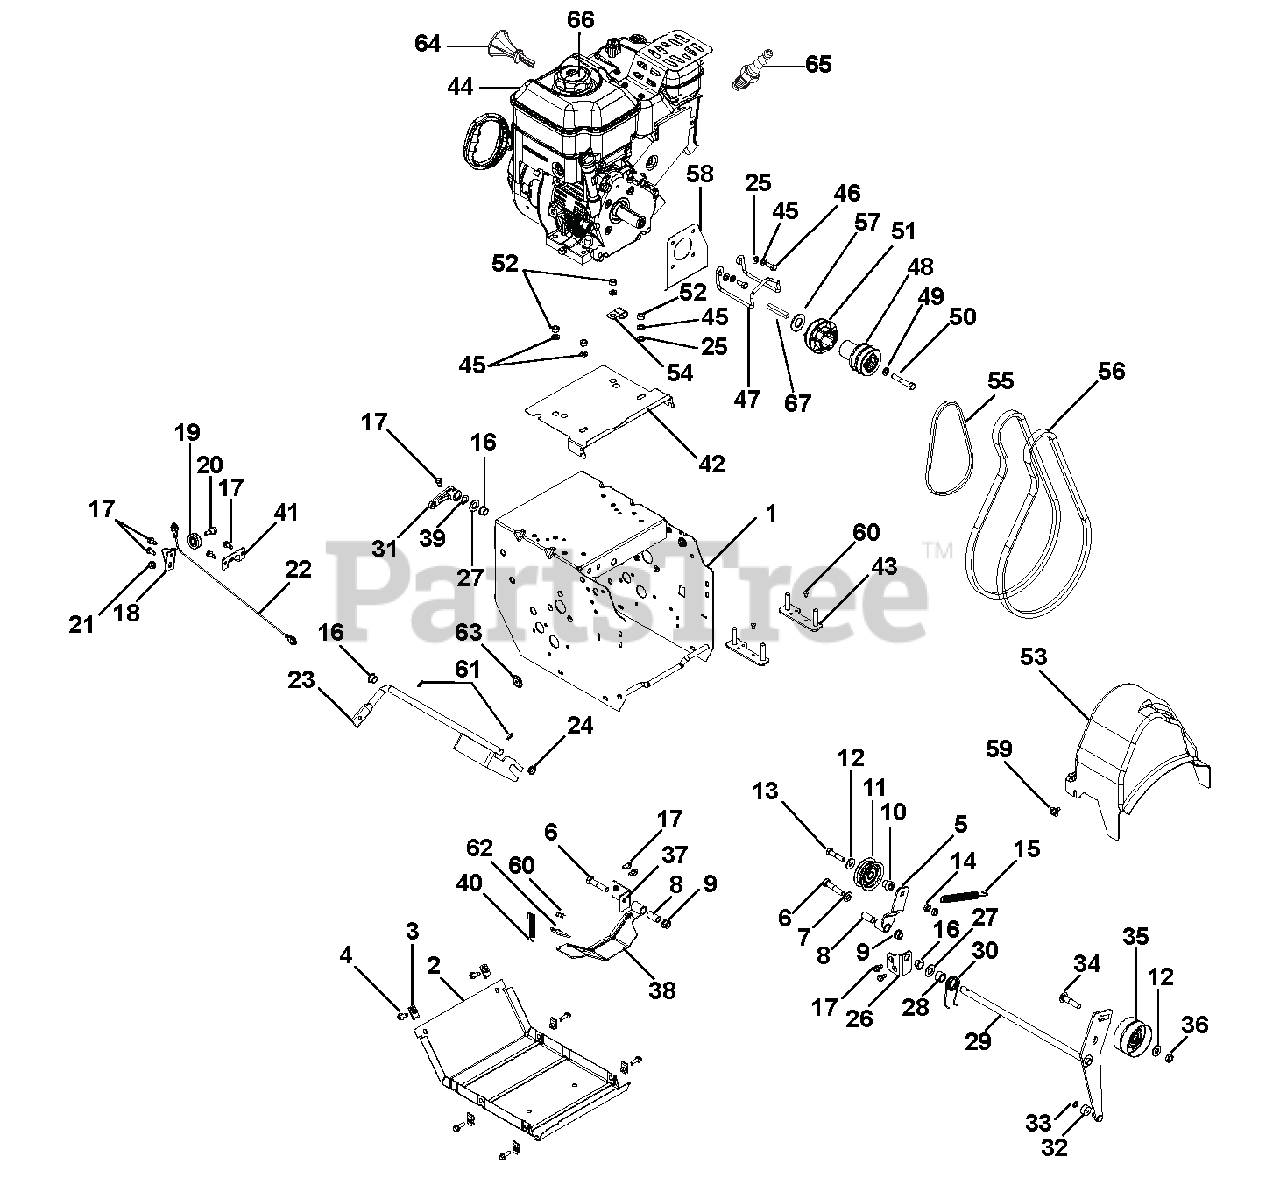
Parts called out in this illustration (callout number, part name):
1	FRAME, 920/921
2	COVER, BOTTOM
3	NUT-RTNR .25-20X.56
4	BLT-HEX .25-20X.75 HWH YZ GR5
5	WELDMENT, TRACTION IDLER ARM
6	@BLT-HEX .38-16X1.75 GR5 YWZC
7	@WSHR-FL-STL.406X.812X.065 YWZ
8	BSHG-SLV .385X.500X1.045
9	@NUT-LK-TOP-FLG .38-16 YWZC
10	SPCR, BRG .315X.50X.688X.281
11	IDLER
12	@WSHR-FL-STL.38X.875X.083 YWZC
13	@BLT-HEX .31-18X1.50 GR5 YWZC
14	@NUT-LK-CTR-JAM .31-18 YWZC
15	SPRING, EXTENSION
16	BUSHING, POLYLINER-.50 SPLIT
17	SCR-TAP .25-20X.50 HWH TR YWZ
18	BRACKET, CABLE PULLEY
19	PULLEY, CABLE
20	BOLT, SHLDR-.375X.375X.25-20
21	@NUT-LK-TOP-FLG .25-20 YWZC
22	CABLE, LOWER TRACTION (DELUXE)
23	WELDMENT, SHIFT FORK
24	BUSHING, POLYLINER-.50 SNAPIN
25	@WSHR-FL-STL.344X.688X.065YWZC
26	BRACKET, MOUNT - IDLER ARM
27	WSHR-FL-STL.531X1.00X.063 YWZC
28	BSHG-SLV .510X.751X.475
29	WELDMENT, ATTACHMENT IDLER ARM
30	SG-TORS .075 X .955
31	ARM, CLUTCH - ATTACHMENT
32	BSHG,SLV .265 X .625 X .375
33	RG-RTNG-EXT .250X.010
34	@BLT-RHDSSQNK .38-16X1.75 G5YZ
35	IDLER, FLAT-2.75 OD X .375 ID
36	@NUT-LK-CTR-JAM .375-16 YWZC
37	BRACKET, BRAKE MOUNT
38	BRAKE ARM W/PAD
39	WSHR-WAVE .50X.75X.015 .13FRHT
40	SPRING-EXT .047 X .438 X 1.85
41	BRACKET, CABLE MOUNT
42	BAFFLE,ENGINE,SMALL BLOCK
42	BAFFLE, BRIGGS MDL 20/21 WATER
43	STRAP, ENGINE BOLT-WELDMENT
43	STRAP, ENGINE BOLT-LARGE BRIGG
44	ENGINE, BRIGGS PF 1150, 120V
44	ENGINE, BRIGGS SNOW 1450, 240V
44	ENGINE, BRIGGS PF 1650, 120V
44	ENGINE, BRIGGS SNOW 1650, 240V
44	ENGINE, BRIGGS SNOW 1150, 240V
45	WSHR-LK .312X.097 HVY YWZC
46	BLT-HEX .31-24X.75 YWZC GR5
47	FINGER, BELT
48	SHEAVE, ATTACHMENT 2-GRV
48	SHEAVE,ATTACHMENT 2-GRV
49	@WSHR-LK .38X.094 REG YWZC
50	BLT-HEX .38-24X2.25 YWZC GR5
51	SHEAVE, DRIVE
51	SHEAVE DRIVE
52	@NUT-HEX .31-18 YWZC
53	BELT COVER
54	J-CLAMP
55	V-BELT, 3L-WRAPPED
56	V-BELT, HA-RAW EDGE (SET)
57	WSHR-FL-STL- 1.062X2.0X.134 YZ
57	WSHR-FL-NYL 1.03 X 1.31 X .134
58	BAFFLE, PRIMARY WATER
59	SCR-TAP .25-20X.5 CAPTIVE
60	RVT-POP .187 YZ
61	CLIP, SPRING
62	PAD, BRAKE
63	PLUG, HOLE - .875" NYLON
64	KEY, IGNITION ROTARY B&S
64	KEY, PUSH/PULL BRIGGS
65	PLUG, SPARK
66	CAP, FUEL - BRIGGS & STRATTON
67	KEY-SQ .25X.625X.25 SAE 8630
